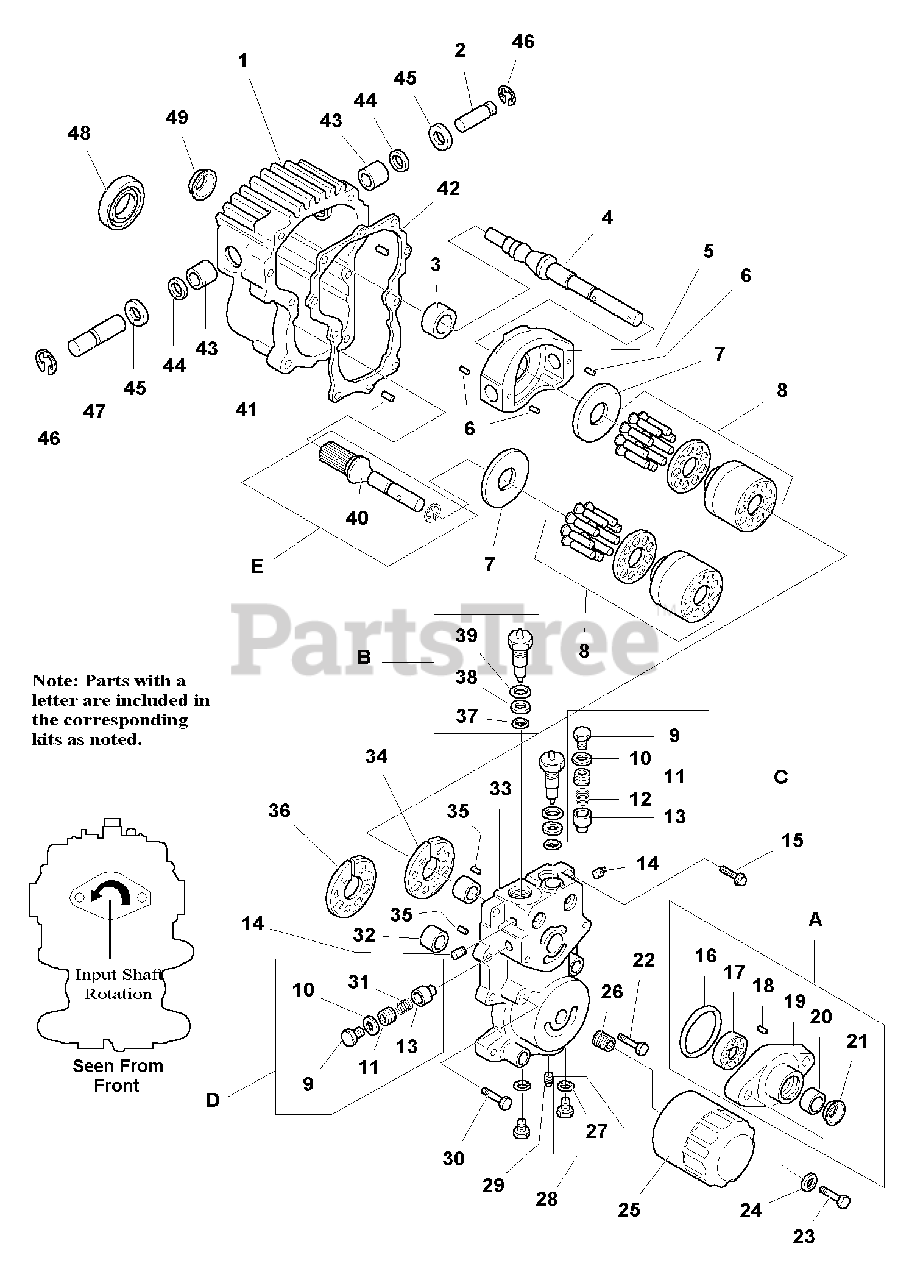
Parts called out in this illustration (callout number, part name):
1	HOUSING ASSEMBLY (Includes Ref. Nos. 49, 43 & 44)
2	SHAFT, Trunnion
3	BEARING, Ball
4	SHAFT, Pump
5	PLATE, Swash
6	PIN, Spring
7	PLATE, Thrust
8	BLOCK, Cylinder
9	PLUG, Hex Head
11	KIT, Shim Pack
12	SPRING, Rel. Valve
13	CONE, Rel. Valve
15	CAPSCREW, 12 Pt.
18	PIN, Straight
19	HOUSING, Charge Pump
20	BEARING, Roller
22	CAPSCREW, Hex Head, 3/6-16 x 1-1/4
23	CAPSCREW, Hex Head, 7/16-14 x 2
24	WASHER, Flat
25	FILTER ASSEMBLY
26	UNION, Filter
28	PLUG, Hex Head. (Includes Ref. No. 27)
29	PLUG, Pipe (Includes Ref. No. 27)
30	CAPSCREW, Hex Head,3/8-16 x 2
31	SPRING, Rel. Valve
32	BEARING, Roller
33	SECTION, Center
34	PLATE, Valve (Pump)
35	PIN, Headless, St.
36	PLATE, Valve (Motor)
38	RING, Back-Up
40	SHAFT, Motor (See Repair Kit "E")
41	PIN, Headless
43	BEARING, Needle
46	RING, Retaining
47	SHAFT, Trunnion
48	BEARING, Ball
A	CHARGE PUMP KIT (Includes Ref. Nos. 16, 17, 18, 19, 20 & 21)
B	CHECK VALVE ASSEMBLY (Includes Ref. Nos. 37, 38 & 39)
C	RELIEF VALVE KIT (Includes Ref. Nos. 9, 10, 11, 12 & 13)
D	RELIEF VALVE KIT (Includes Ref. Nos. 9, 10, 11, 13 & 31)
E	SHAFT & SNAP RING KIT
